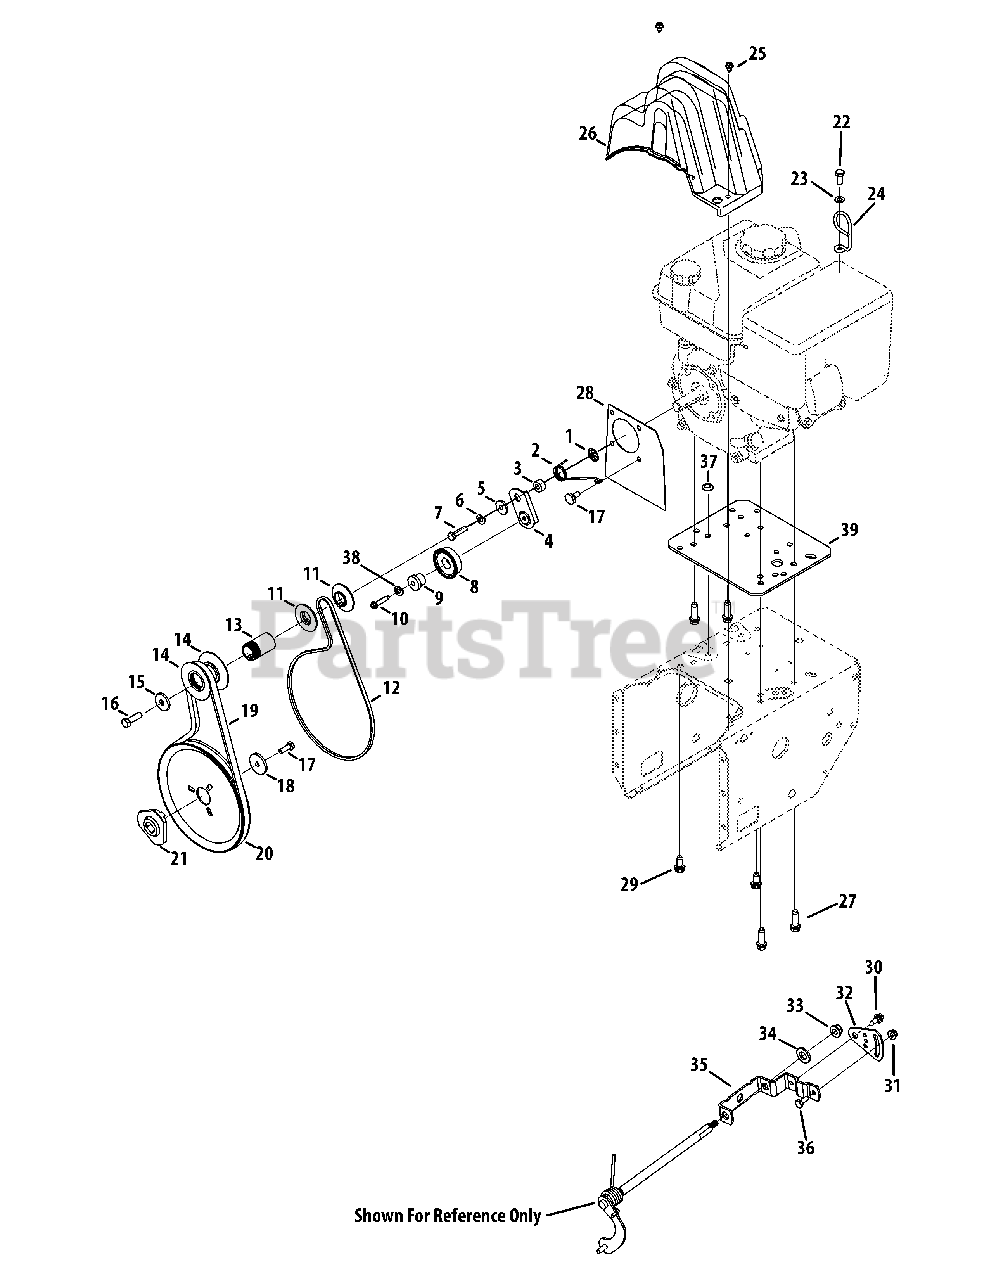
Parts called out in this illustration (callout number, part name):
1	Push-On Nut
2	Torsion Spring, .850 ID x .333
3	Spacer, .340 x .750 x .330
4	Idler Bracket
5	Shldr. Spacer, .3175 ID x .500 x .0975
6	Lock Washer, 5/16
7	Hex Screw, 5/16-24 x 1.25
8	Idler Pulley
9	Shoulder Spacer, .260 x .785 x .538
10	Hex Washer Screw, 1/4-20 x 1.250
11	Pulley Half, 3/8-V x 1.7160 OD
13	Spacer, .875 ID x 1.185 OD
14	Pulley Half, 4L-V x 2.600 OD
15	Flat Washer, .406 x 1.25 x .157
16	Hex Screw, 3/8-24 x 1.25
17	Shoulder Screw, .500 x .145
18	Flat Washer, .34 x 1.50 x .150
19	Belt
20	Auger Pulley
21	Adapter Pulley
22	Hex Screw, M8-1.25 x 20
23	Flat Washer, .330 x .630 x .0635
24	Cable Control Wire
25	Hex Washer Screw, 1/4-20 x .375
26	Belt Cover
27	Hex Washer Screw, 3/8-16 x 1.250
28	Cover Plate
29	Hex Washer Screw, 3/8-16 x .75
30	Shoulder Screw, .368 x .113 x 1/4-20
31	Flange Lock Nut, 1/4-20
32	Speed Selector Pivot Bracket
33	Flange Lock Nut, 5/16-18
34	Flat Washer, .469 x .875 x .105
35	Speed Selector Shift Bracket
36	Hex Screw, 1/4-20 x .620
37	Plug, 3/8 ID
38	Lock Washer, 1/4
